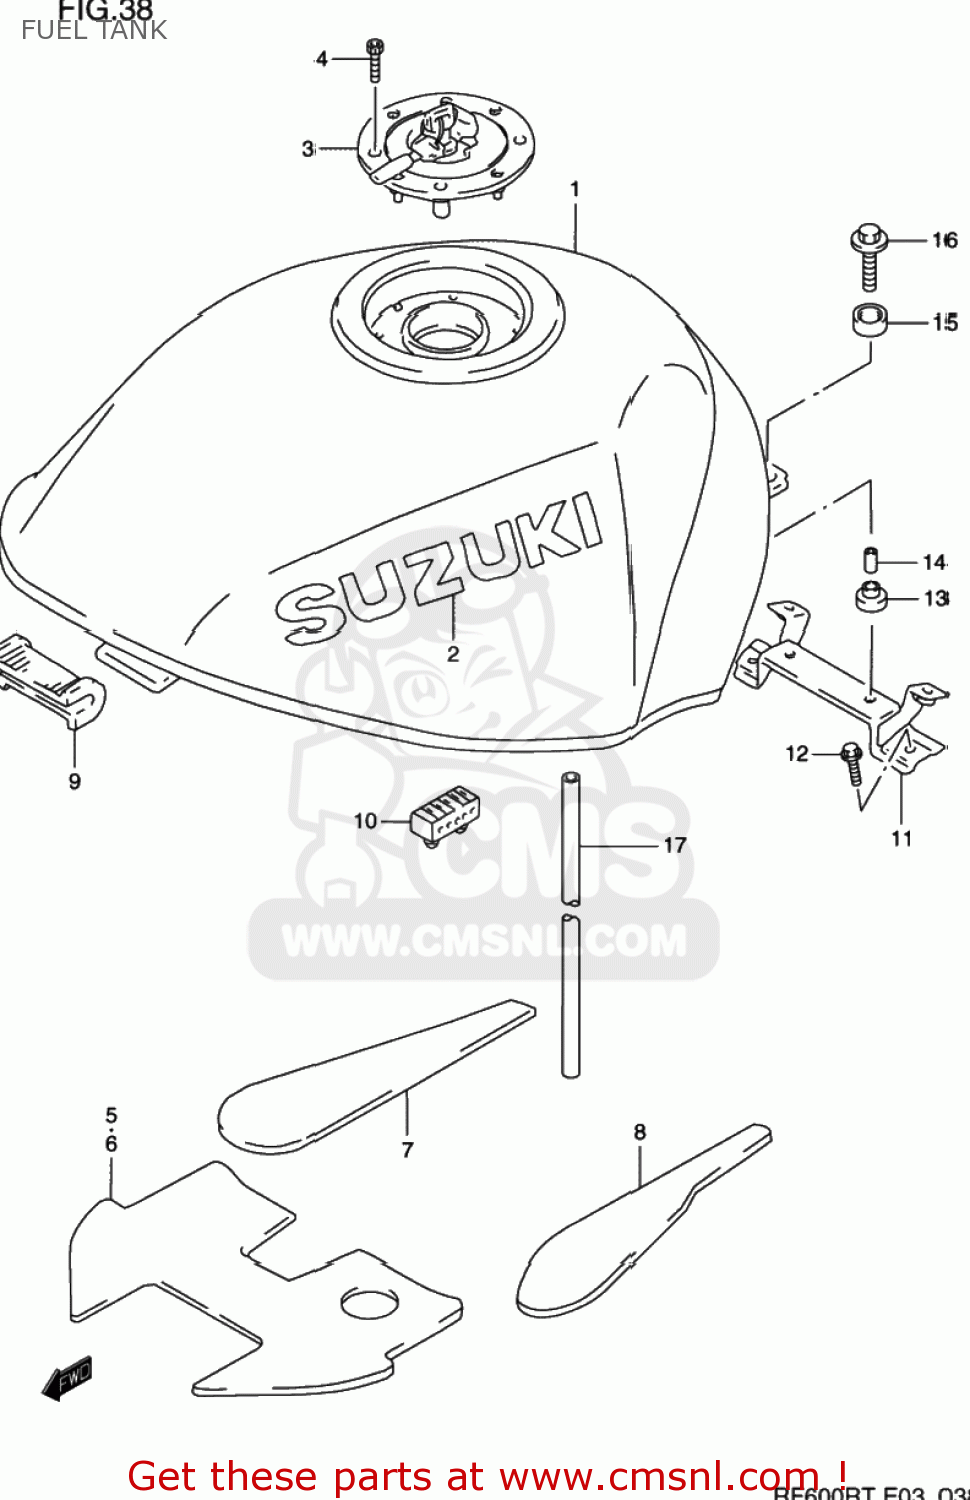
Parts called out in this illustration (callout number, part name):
1	TANK ASSEMBLY,FUEL
2	EMBLEM,FUEL TANK
3	CAP SET,FUEL TANK
4	BOLT(5X20)
5	SHIELD,FUEL TANK HEAT NO.1
6	SHIELD,FUEL TANK HEAT NO.1
7	SHIELD,FUEL TANK HEAT NO.2
8	SHIELD,FUEL TANK HEAT NO.3
9	CUSHION,FUEL TANK FR
10	CUSHION,SEAT(40X20X15)
11	BRACKET,FUEL TANK RR
12	BOLT
13	CUSHION
14	SPACER
15	CUSHION
16	BOLT
17	HOSE(7X10.2X600)
